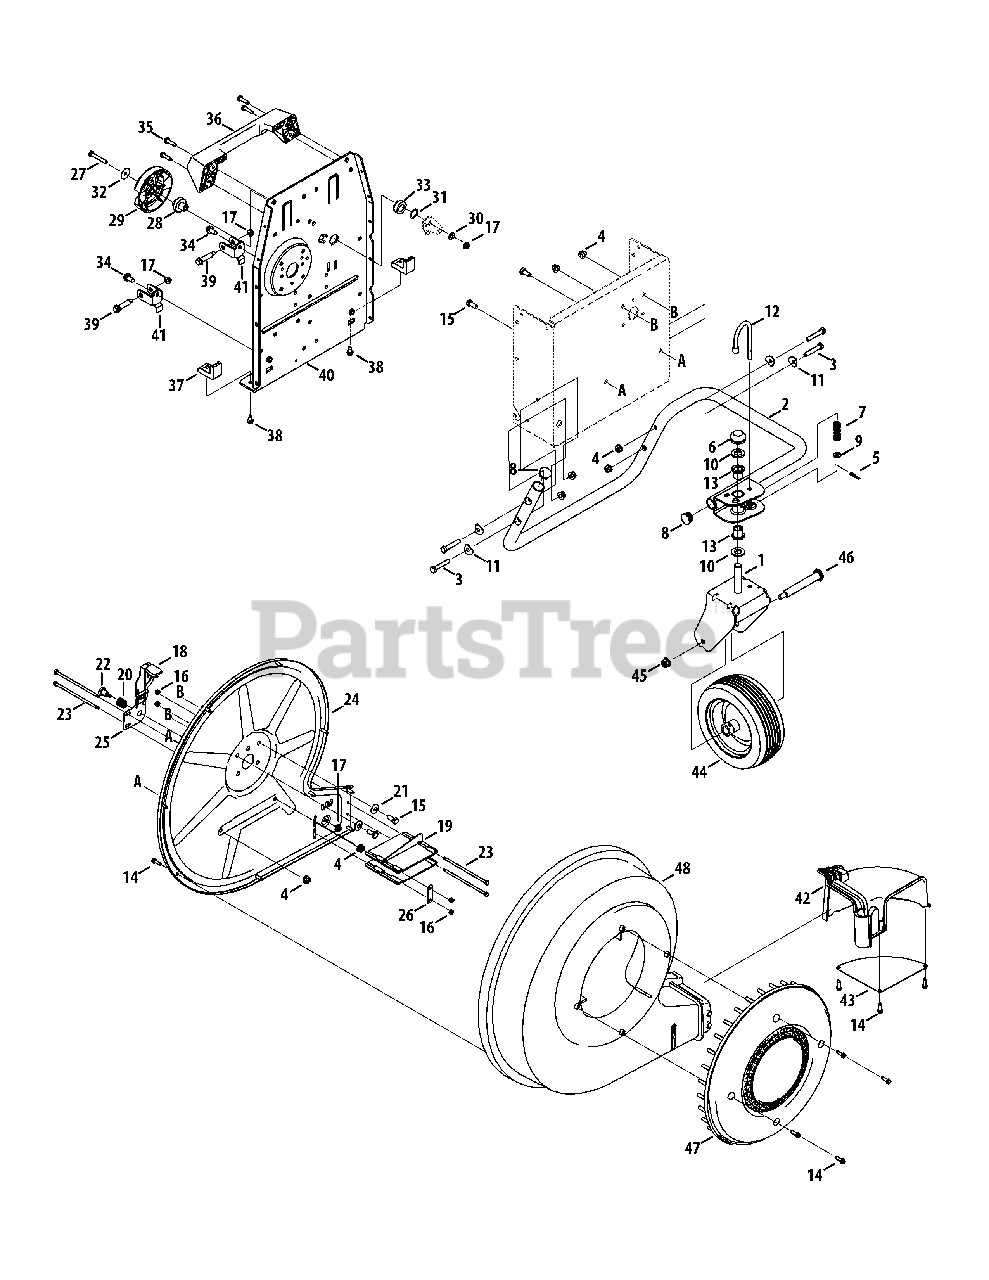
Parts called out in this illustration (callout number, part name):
1	Caster Wheel Bracket Assembly
2	Lower Frame Assembly
3	Hex Cap Screw, 5/16-18 x 1.75
4	Flange Lock Nut, 5/16-18
5	Cotter Pin, .072 Dia. x 1.13 Lg.
6	Push Cap, 5/8
7	Compression Spring, .531 x 1.75 Lg.
9	Flat Washer, .330 x .630 x .064
10	Flat Washer, .640 x 1.120 x .125
11	Saddle Washer, .320 x .93 x .060
13	Flange Bearing, .631 ID
14	Hex Screw, #12-16 x .75
15	Hex Cap Screw, 5/16-18 x .75
16	Hex Lock Nut, #8-32
17	Flange Lock Nut, 1/4-20
18	Height Adjustment Knob
19	Louver Blower Plate
20	Compr. Sprng., .515 x .641 x .95
21	Bell Washer, .340 x .872 x .060
22	Shoulder Screw, .437 x .50 x 1/4-20
23	Shoulder Screw, .18 x 4.8 x 8-32
25	Louver Blower Lever
26	Louver Guide Plate
27	Hex Cap Screw, 1/4-20 x 1.75
28	Clutch Link Shaft
29	Idler Clutch
30	Bell Washer, .265 x .75 x .062
31	Wave Washer, .65 ID x .855 x .010
32	Flat Washer, .265 x 1.0 x .030
33	Hex Flange Bearing 5/8 PM
34	Hex Washer Screw, 5/16-18 x .750
35	Self-tapping Screw, 1/4-20 x 1.00
36	Rear Handle
37	Bumper Pad
38	Shoulder Screw, 1/4-20 x 0.50
39	Shoulder Screw,, 1/4-20 x .375 x 1.355
40	Frame Mounting Bracket
41	Support Bracket
42	Chute Assembly
44	Complete Wheel, 8 x 3
45	Flange Lock Nut, 3/8-16
46	Shoulder Screw, 3/8-16 x .625 x 3.94
47	Blower Cover
48	Blower Housing
